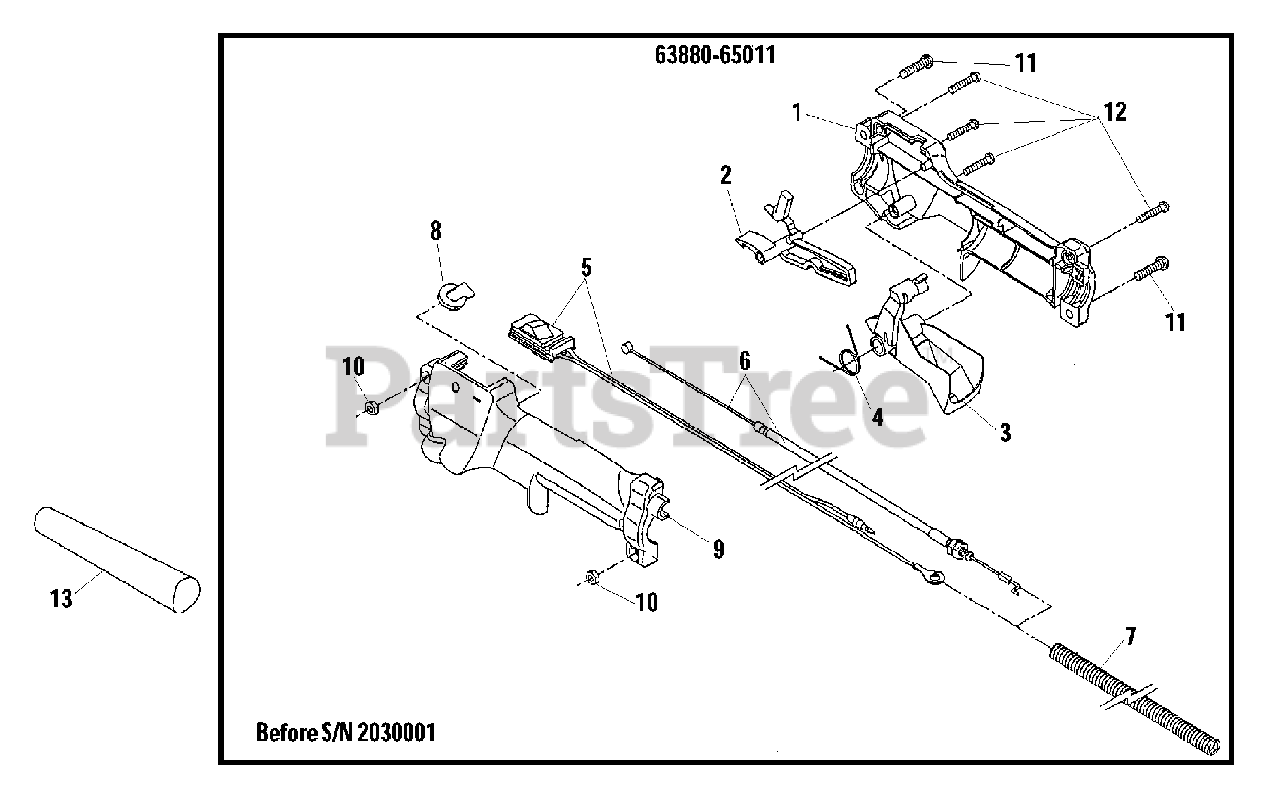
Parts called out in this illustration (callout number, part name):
1	HANDLE, CONTROL - RIGHT
2	LEVER, LOCK
3	LEVER
4	SPRING
5	SWITCH, IGNITION
6	CABLE, THROTTLE
7	TUBE
8	PLUG
9	HANDLE, CONTROL - LEFT
10	NUT - 5
11	SCREW - 5X20
12	SCREW - 4X20 -- TAPPING
13	COLLAR
63880-65011	THROTTLE LEVER ASSY
